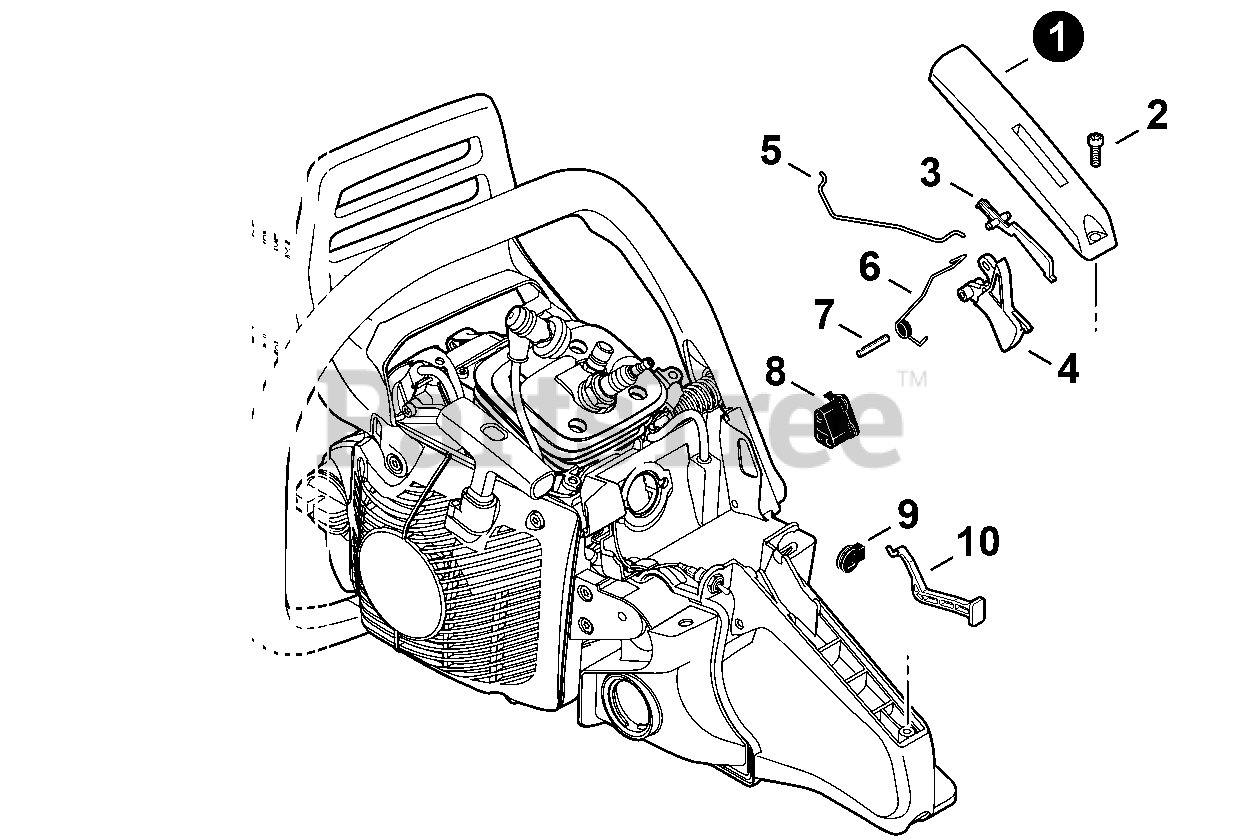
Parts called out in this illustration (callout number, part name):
1	COVER, HANDLE
2	SCREW - 4×12
3	LEVER, THROTTLE LOCKOUT
4	TRIGGER, THROTTLE
5	ROD, THROTTLE
6	SPRING, TRIGGER
7	PIN, SPRING - 4×25
8	GROMMET, NEEDLE
9	GROMMET, CHOKE
10	ROD, CHOKE
